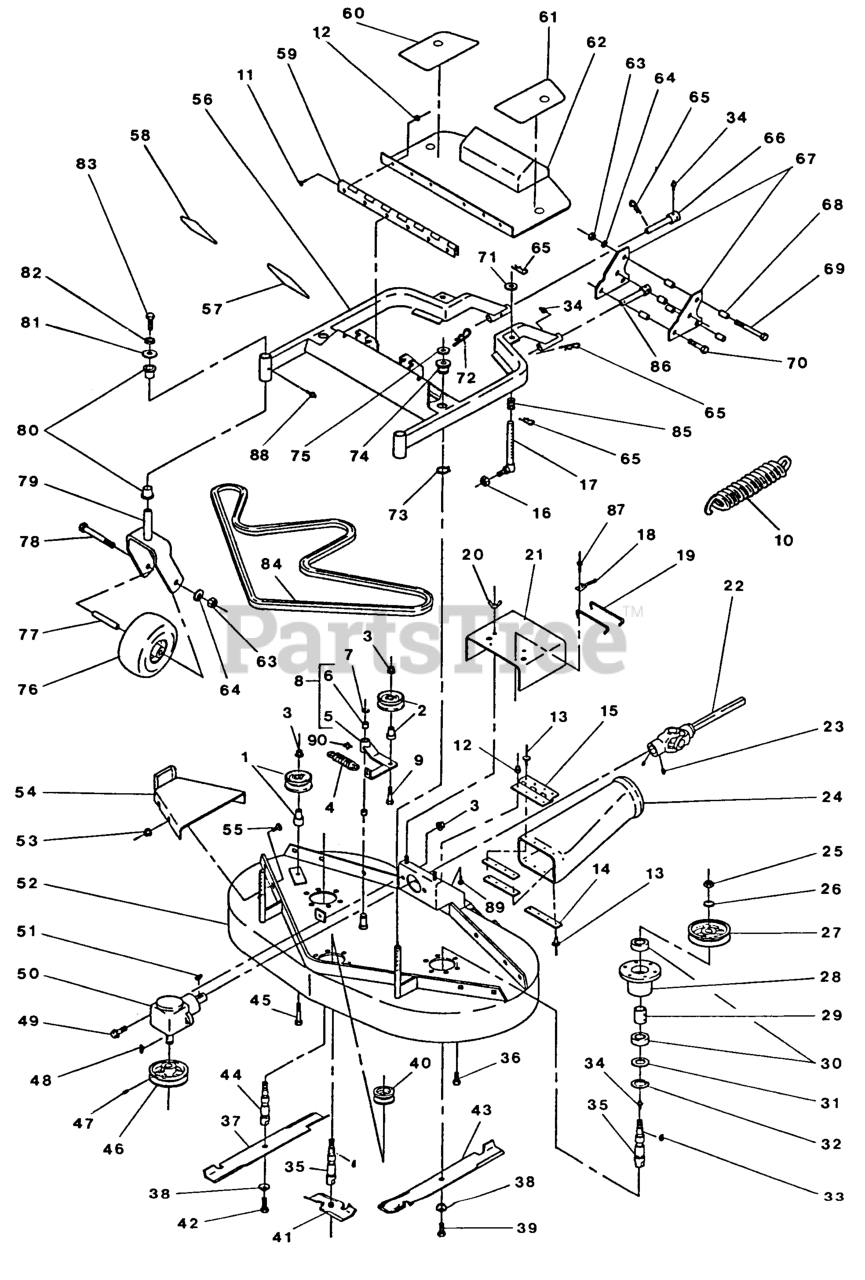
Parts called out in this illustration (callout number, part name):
1	KIT,IDLER & BUSHING
4	SPRING-IDLER, DECK
6	SLEEVE-BEARING
18	CLIP-DECK, HOLD UP ROD
20	WINGNUT-NYLOCK
22	PTO SHAFT,SHAFT HALF PNT
26	WASHER-SPRING
27	SHEAVE,BLADE DRIVE
29	SPACER,BEARING
31	SEAL,MECHANICAL DUST
32	RING,SNAP WLDS N5000-244
38	WASHER-SPRING
42	SCREW-CAP,HH
47	SCREW-SET
50	GEARBOX, PEERLESS
57	PAD,ANTI SKID UPPER LH
58	PAD,ANTI SKID UPPER RH
59	HINGE,FLOORPAN
60	PAD,ANTI SKID LOWER RH
65	PIN,HAIR COTTER
74	BUSHING-DECK
75	WASHER-FLAT
80	BEARING-FLANGED
85	SPRING,HITCH RELEASE
87	Pop Rivet, Steel 3/16 X .250
89	BOLT-CARR
